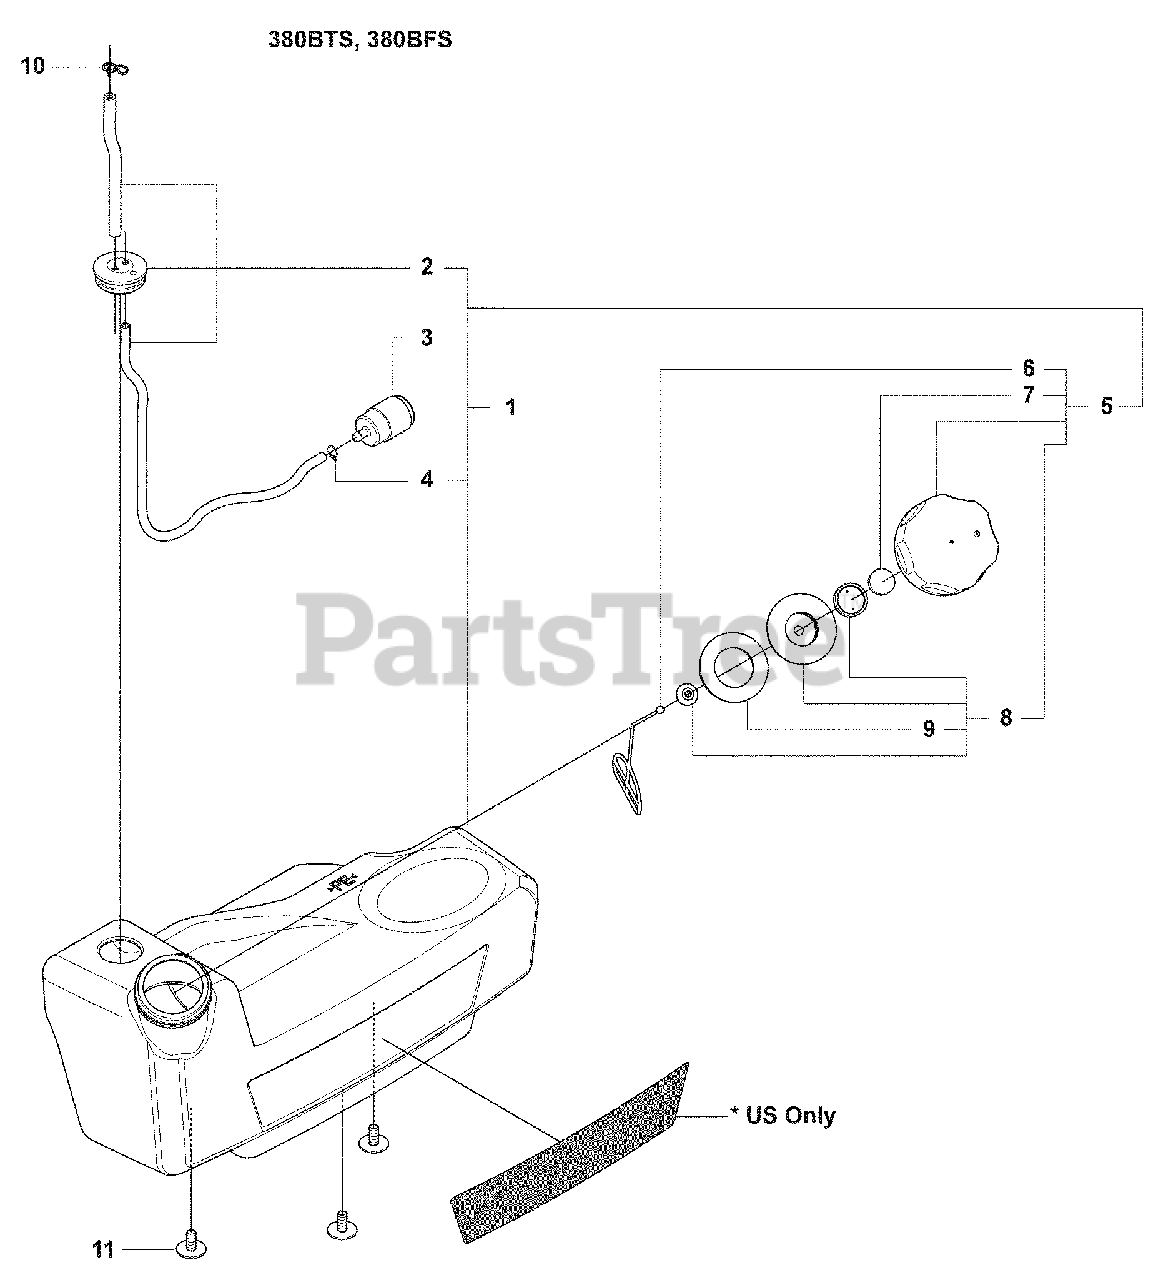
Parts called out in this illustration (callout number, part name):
2	Pipe, Complete
3	Fuel Filter Assembly
4	Clip
5	Fuel Cap Assembly
7	Air Filter
8	Holder, A
9	Packing
10	Clip
